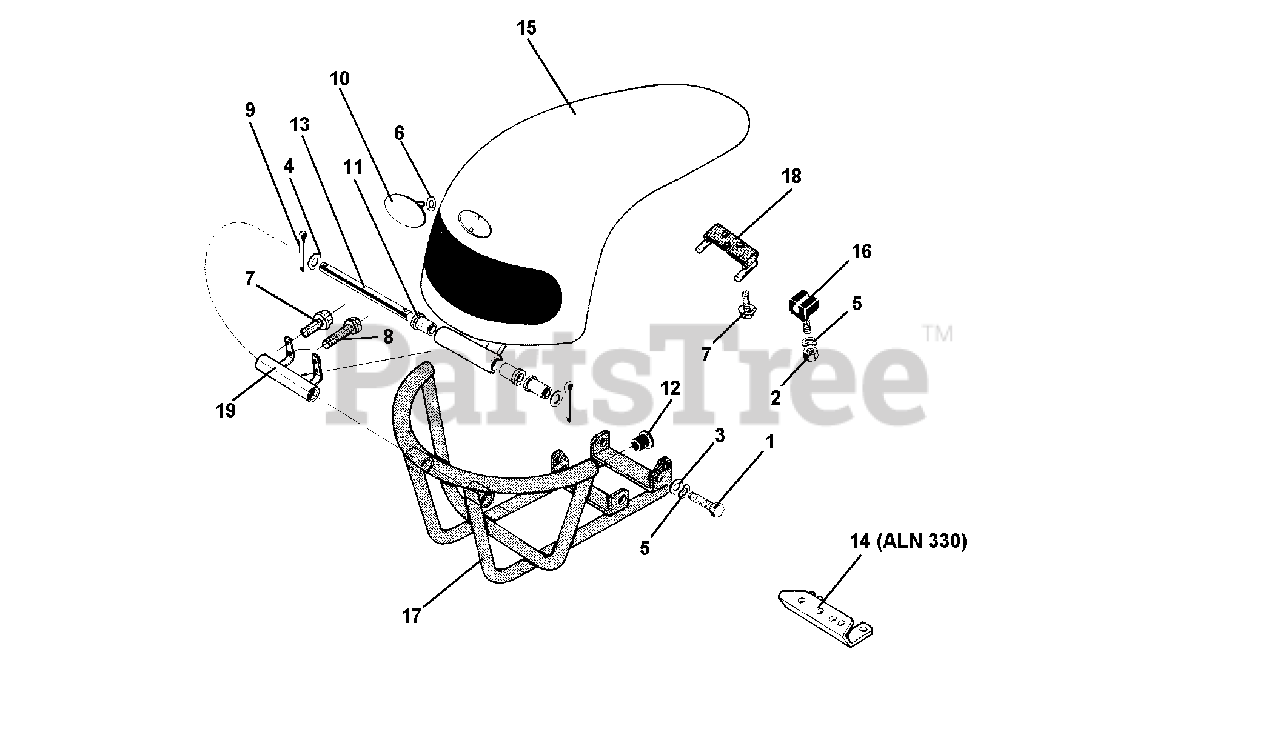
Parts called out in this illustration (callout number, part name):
1	SCREW M8 X 20
3	WASHER, FLAT 8.4
4	FLAT WASHER 10.5 X 21
5	WASHER, LOCK 8.4
6	WASHER, LOCK FOR PINS
7	SCREW AF 6.3 X 16
8	SCREW AF 6.3 X 38 UNI 6950
9	PIN, COTTER A 3 X 20 UNI 1336
13	PIN, COUPLING
14	COVER RUBBER PAD SUPP. ALN 330
17	COMPLETE BUMPER
18	COVER UPPER STOP
19	COVER COUPLING BRACKET
